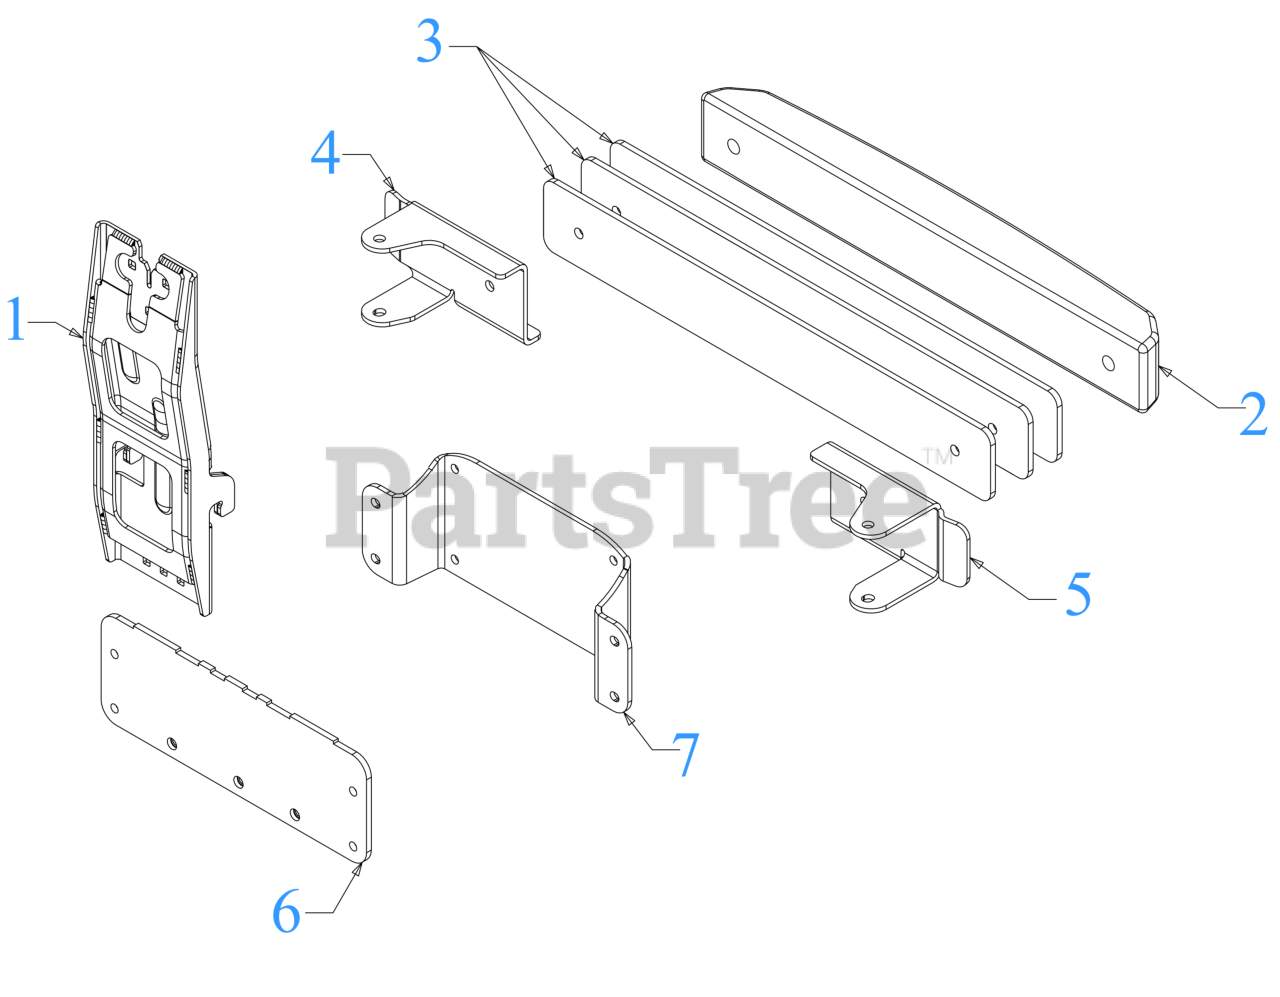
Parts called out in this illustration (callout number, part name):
1	VERTICAL SUPPORT BRACKET
2	BAGGER WEIGHT
3	WEIGHT PLATE
4	WEIGHT BRACKET (LH)
5	WEIGHT BRACKET (RH)
6	BAGGER MOUNTING PLATE
7	BAGGER BUMPER BRACKET
